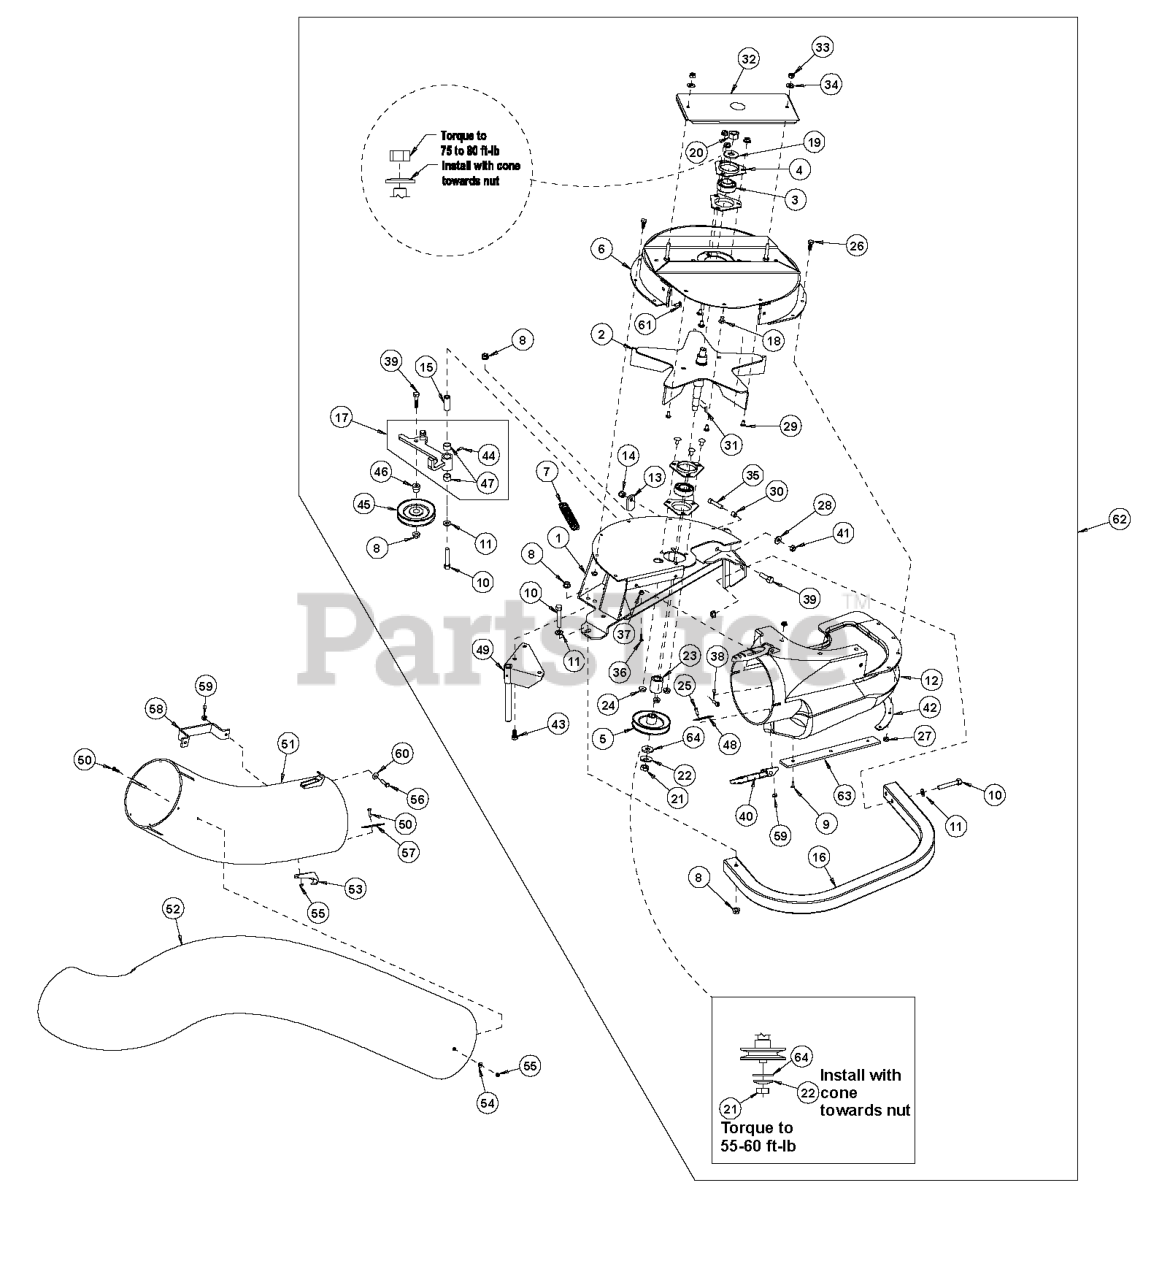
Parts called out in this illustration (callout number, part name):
1	Wld, Blower Mount 60"&72"
2	Wld, Impeller
3	Bearing, SPH OD
4	Housing, Flange
5	Sheave, Blower
6	Wld, Upper Housing (103-0457-03) With Decals
7	Spring, Idler
8	3/8-16 Whizlock Nut
10	Screw HH 3/8-16 x 2 1/4
11	Washer, Flat 438 x 100 x 083
12	Asm, Blower Chute
13	Latch, Grass Catcher
14	Nut, Nyloc 3/8-16
15	Bushing, Idler Pivot
17	Asm , Idler W/Bushings (103-0462-03) Zerk, & Decal
18	Bolt, Carriage 5/16-18 x 5/8
19	Washer, Spring Disc
20	Nut, 5/8-18
21	Nut, Jam 1/2-20
22	Washer, Spring Disc
24	Nut, Whizlock 5/16-18
25	Screw, HH 1/4-20 x 3/4
26	Screw, HH 1/4-20 x 5/8
27	Nut, Whizlock 1/4-20
28	Washer, Spring Disc 5/16
29	Bolt, Carriage 1/4-20 x 5/8
30	Bushing, Locator
31	Key, Woodruff #61 5/8 x 3/16
32	Cover, Bearing (103-3584-03)With Decal
33	Nut, Nyloc 5/16-18 (thin)
34	Washer, Flat 5/16 x 7/8 OD
35	Screw, Socket HD 5/16-18 x 1 1/4
36	Screw, CRTH #10-24 x 3/4
37	Nut, Whizlock #10-24
38	Screw, CRTH 1/4-20 x 3/4
39	Screw HH 3/8-16 x 1 1/2
40	Latch, Rubber
41	Nut 5/16-18
42	Plate, Blower Backing
43	Screw HH 3/8-16 x 3/4
44	Zerk, 1/8-28 Straight
45	Pulley, Idler
46	Hub, Spacer
47	Bearing
48	Plate, Backing
49	Wld, Mount Pin
50	Screw, HWH #10-24 x 3/4
51	Tube, Lower
52	Tube, Upper 60"
52	Tube, Upper 66" & 72"
53	Latch, Catch
54	Washer, Flat 216 x 75 x 05
55	Nut, Nyloc #10-24
56	Screw, HH 1/4-20 x 1
57	Plate, Backing
59	Nut, Nyloc 1/4-20
60	Washer, Flat 26 x 125
61	Bolt, Carriage 1/4-20 x 3/4
62	Asm, Blower (Includes Items 1-49,61, 63 & Decals)
63	Plate, Reinforcement
64	Washer-1/2 SAE
65	Nut-Nyloc
